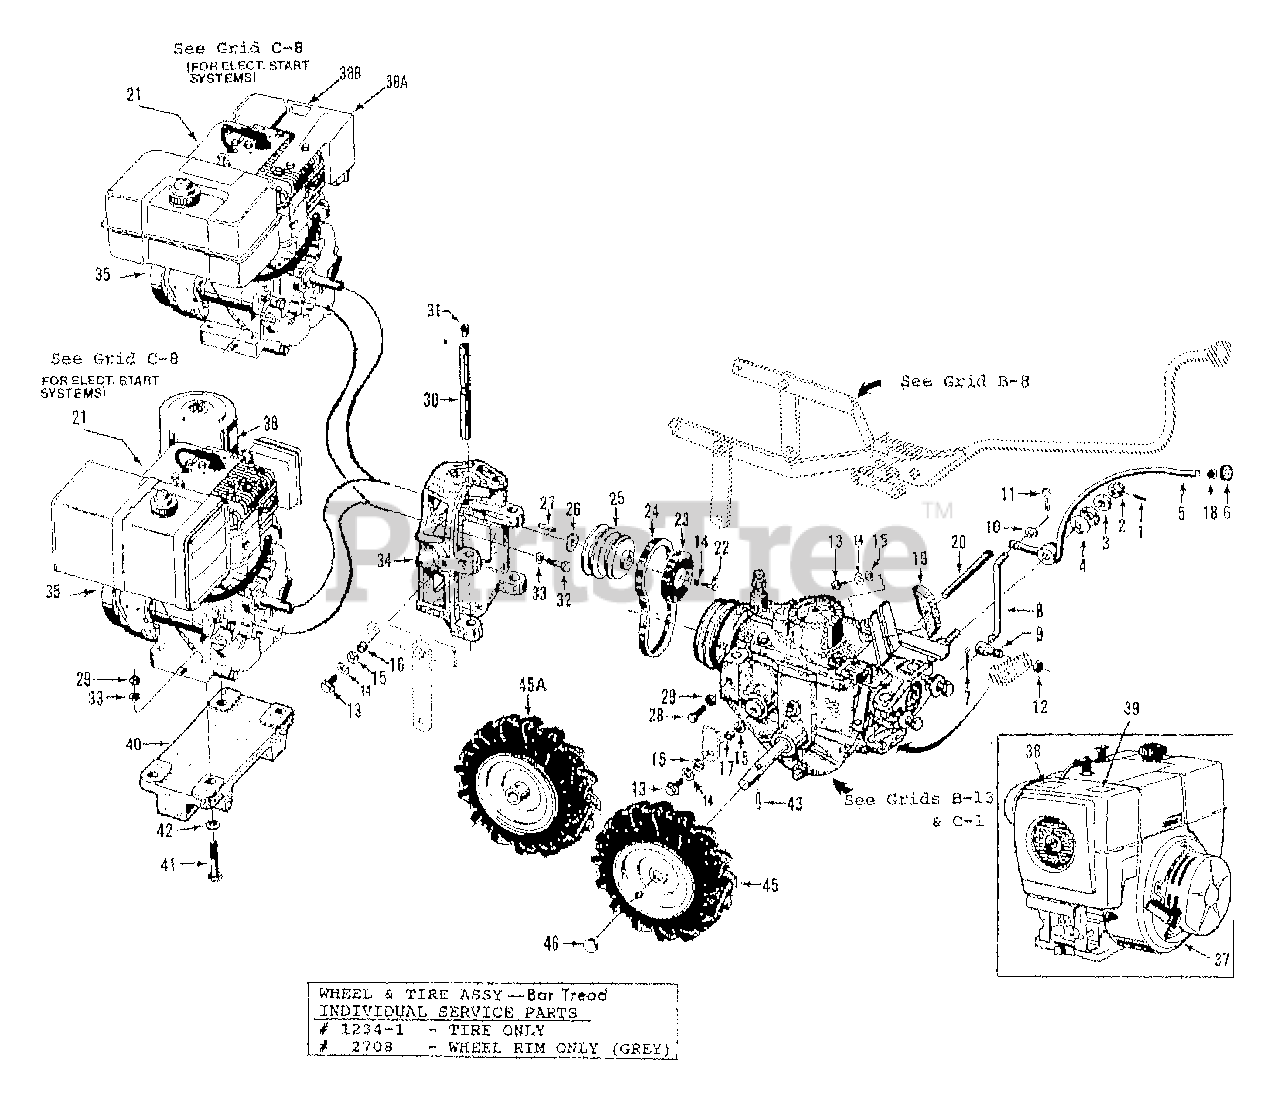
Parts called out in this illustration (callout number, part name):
1	PIN-SPRING .125 X 1
2	NUT-HEX 1/2-20 (SLOTTED)
3	WASHER-# SHOULDER ZP
4	WASHER-# 1.97X1X.118
5	LVR-W/KNOB (WHEEL SPEED) (INCL. 6 & 18)
6	KNOB-WHEEL SPEED HORSE (INCL. 18 & PLASTIC DECAL INLAY)
7	PIN-COTTER .094X1.0
8	ROD-CONNECTING
9	SWIVEL
10	WASHER-FLAT 5/16 SAE
11	PIN-CLIP .08
12	NUT-H/LK 5/16-18
13	SCR-HH 3/8-16X1.0 G5 ZP
14	WASHER-LK .375 @ DEPL
15	WASHER-FLAT 3/8 SAE
16	THIS REF. NO. NOT USED
17	BUSHING-.5X.375X.3
18	RING-TOLERANCE .5325 ID
19	KIT-ADJ BLOCK 4 SP (INCL. 13, 15 & 20)
20	BAR-ADJUST, 7" W/MEASURING GAUGE
21	DECAL-STARTING STABIL, B&S
22	SCR-HH 3/8-24X1.5 G5
23	KIT-ADJ BLOCK/REV DISC (INCL. 19)
23	DISC ONLY - REVERSE, RUBBER RIMMED
24	BELT-FORWARD DRIVE
25	PULLEY-ENG MACH
26	SHIM-1.0X.7656X.062
26	SHIM-1.0X.7656X.031
27	KEY-.188 SQ X 2.33
28	BOLT-HEX HD., 5/16-18x1", GR 5
29	NUT-HEX 5/16-18 ZP
30	BAR-ENG MTG W/CAP PLUG
31	PLUG-CAP (RED)
32	BOLT-HH 5/16-24X1.125 G5 ZP
33	WASHER-LK .312 ZP
34	MOUNT-MOTOR HSE OPC PNT
35	TILLER-7HP STD HORSE
35	TILLER-7HP EL HORSE
35	TLR-HORSE 8HP STD B&S
35	TILLER-8HP EL HORSE B&S
35	OBS-HORSE 7HP STD CA
35	OBS-HORSE 7HP ELC CA
35	TILLER-8 T/B STD HORSE I/P B&S
35	TILLER-8HP T/B EL HORSE B&S I/P
37	TILLER-8HP STD PRO HORSE
37	TILLER-8HP EL PRO HORSE
37	OBS-HORSE 8HP STD CA
37	OBS-HORSE 8HP ELC CA
37	TILLER-7HP T/B STD HORSE
37	TILLER-7HP T/B ELEC HORSE
38	DECAL-HOT SURFACE
38A	GUARD-MUFFLER
38B	DECAL-HOT SURFACE
39	DECAL-STABIL STARTING
40	WEIGHT-ENG ECONO PNT
41	SCR-HH 5/16-18X2.25 G5ZP
42	SPACER-.88X.385X.09 ZP
43	PIN-SPIROL .313 X 1.5
45	ASSM-TIRE&WHEEL LH GRAY
45A	ASSM-TIRE&WHEEL RH GRAY
46	CAP-HUB BLK PLASTIC (REPLACES 9145)
